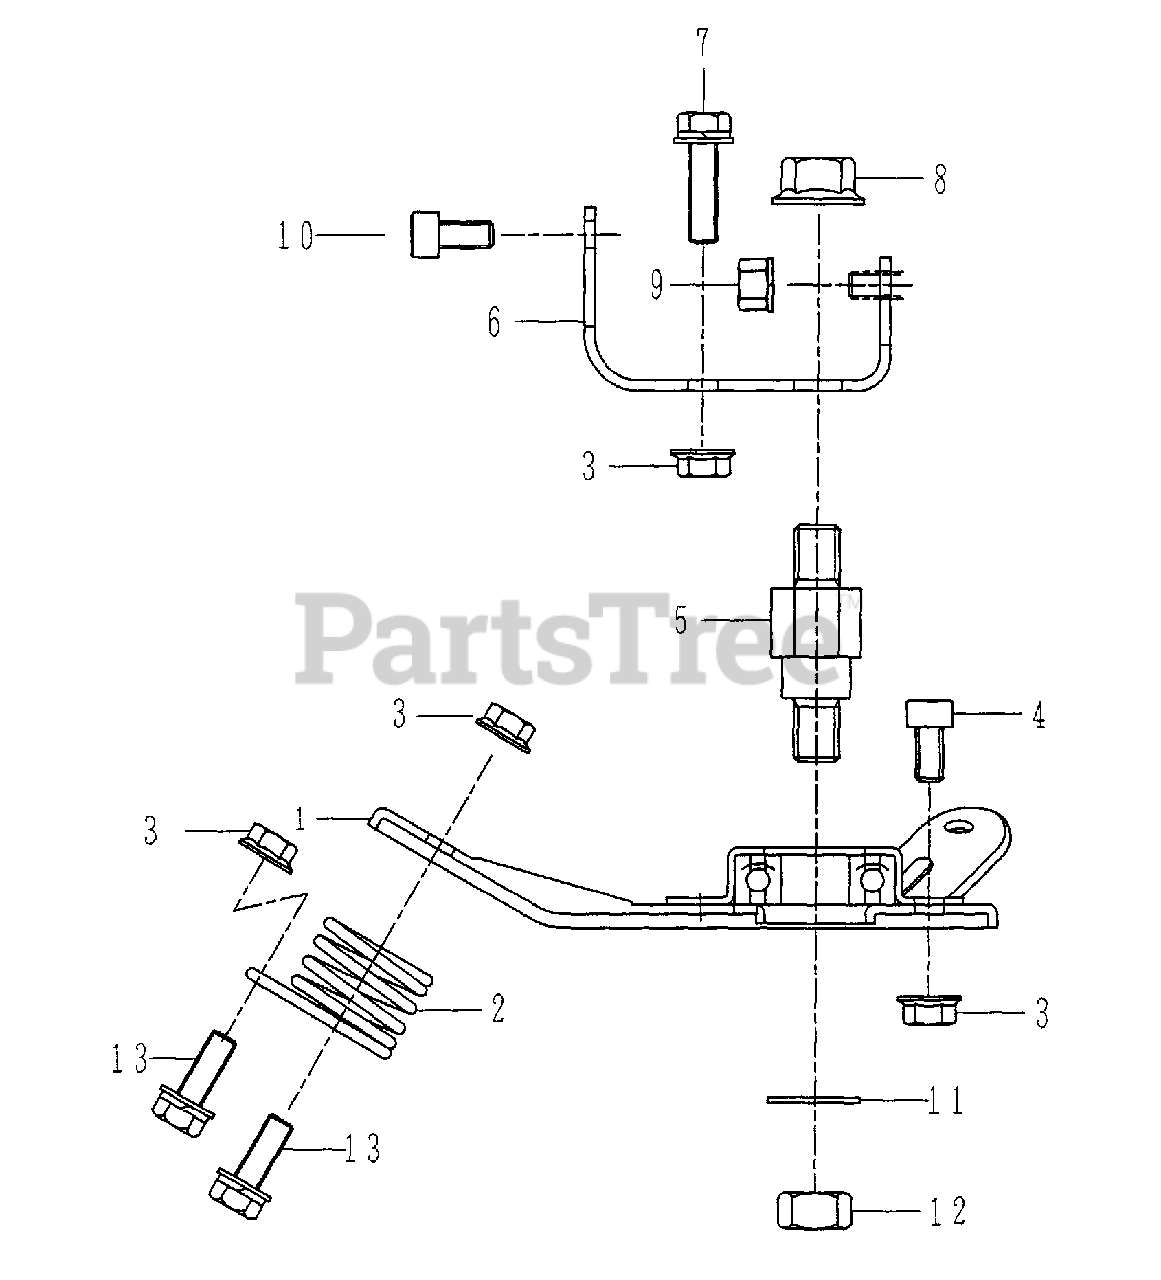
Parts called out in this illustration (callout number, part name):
1	BRACKET, SWIVEL
2	SPRING
3	NUT
4	BOLT
5	SHAFT, MOUNTING
6	BRACKET
7	BOLT
8	NUT - FLANGE
9	NUT - 5 -- FLANGE
10	SCREW - 5X12
11	LOCKWASHER
12	NUT
13	BOLT
